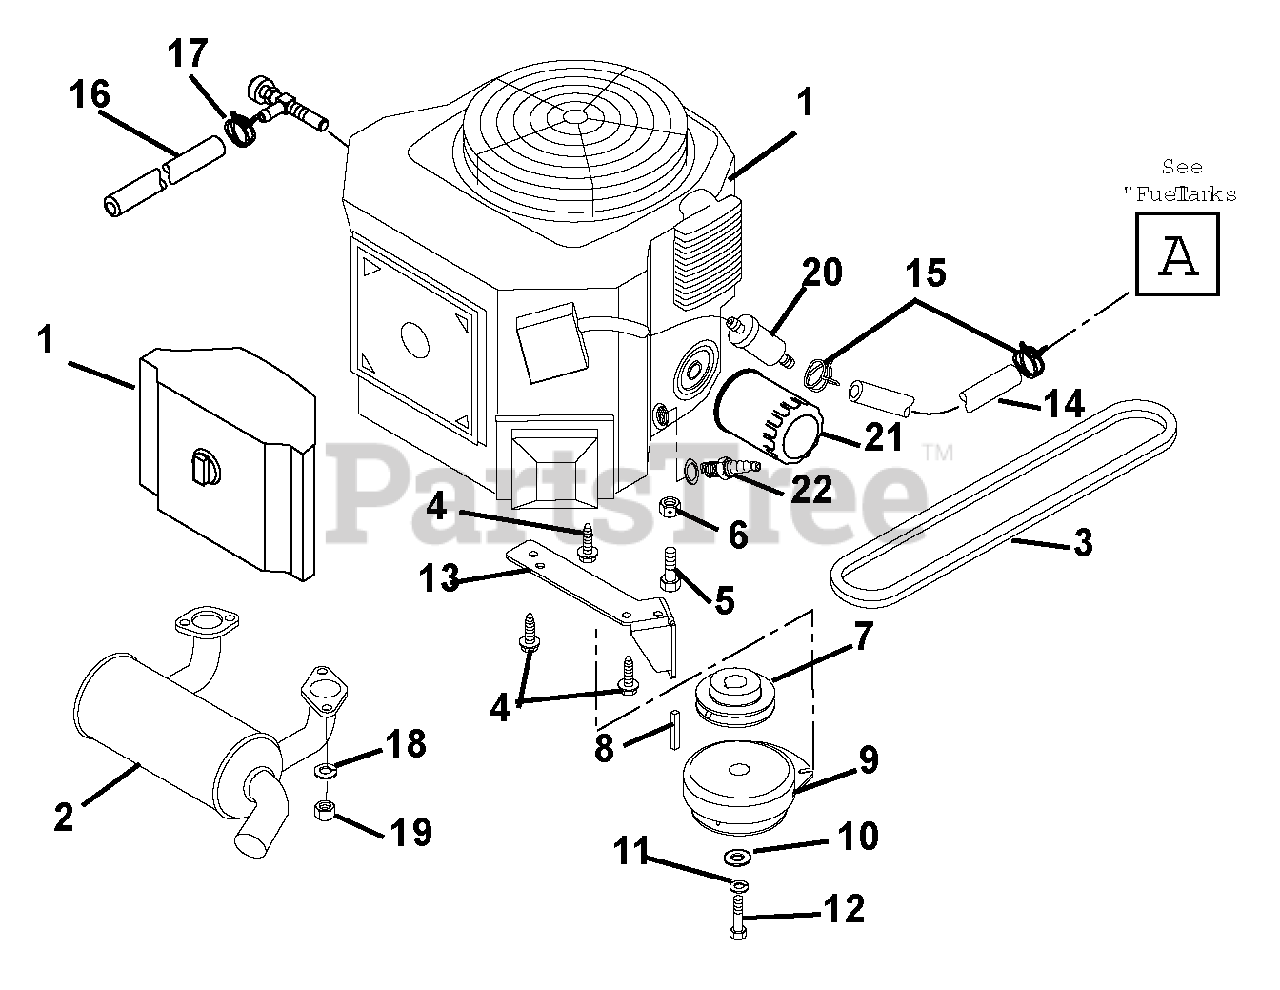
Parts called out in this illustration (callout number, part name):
1	Engine, 15HP Kawasaki FH451V (056, 314)
1	Engine, 17HP Kawasaki FH500V (065)
2	Muffler, Kawasaki
3	V-Belt, 53.7 Inches
4	Screw, Tapping Hex Washer Head .38-16 x 1.00
5	Bolt, Hex .31-18 x 1.50 Grade 5
6	Nut, Locking Top Flange .31-18
7	Pulley, V 4.00 x 1.00
8	Key, Square .25 x .625 x .25 SAE 8630 OR SAE 1035
9	Clutch, Electric
10	Washer, Flat Steel .469 x 2.00 x .250
11	Washer, Locking .44 x .109
12	Bolt, Hex .44-20 x 2.50 Grade 5
13	Clutch, Stop
14	Hose, Gas Line 6.25"- .25" I.D.
15	Hose, Clamp
16	Hose, .50 x 6.00
17	Clamp, .88 Diameter Hose
18	Washer, Lock .31 x .078 Regular
19	Nut, Hex M8-1.25
20	Fuel Filter, Kawasaki
21	Oil Filter, Kawasaki
22	Spark Plug, Kawasaki
